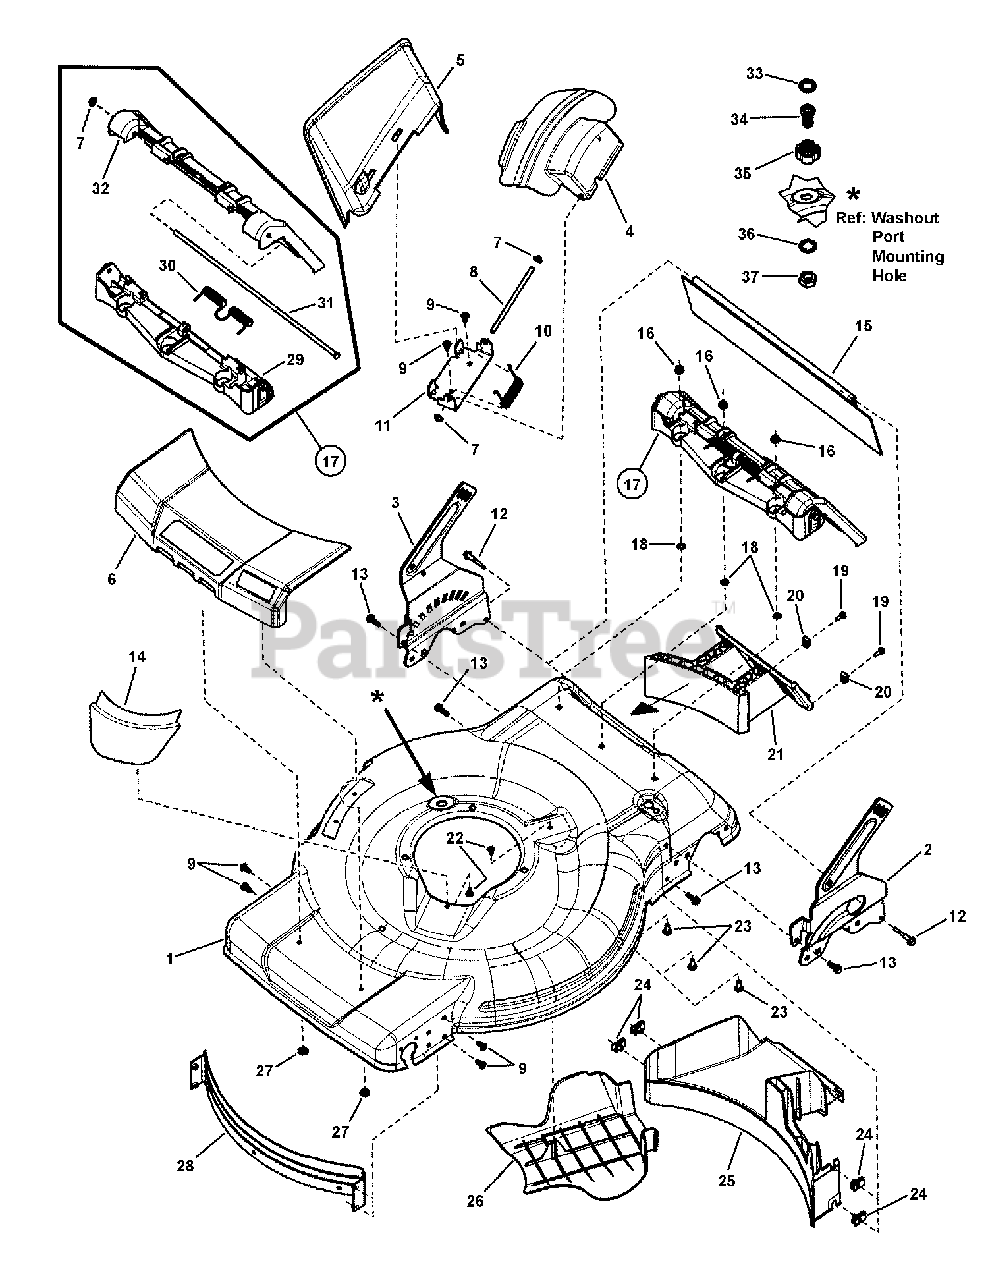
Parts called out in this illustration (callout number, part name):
1	DECK, 22", Rear Wheel Drive, Washout
1	DECK, 22", Rear Wheel Drive, Washout, Electric Start
2	BRACKET, Lower Handle, LH, 22 WBM
3	BRACKET, Lower Handle, RH, 22 WBM
4	COVER, Mulching
5	CHUTE, Side Discharge, 22" WBM
6	COVER, Front, Push/Rear Wheel Drive
7	PUSHNUT, 1/4"
8	ROD, Pivot
9	SCREW, 1/4-20 x .550 Self-Tap (Torx)
10	SPRING, Torsion
11	BRACKET, Chute
12	BOLT, 1/4-20 x 1-1/2" Shoulder
13	BOLT, 1/4-20 x 3/4" Hex Flange Lock, GR 5
14	DEBRIS SHIELD, Front
15	GUARD, Rear 22"
16	NUT, 1/4-20 Hex Flange Lock
17	ASSEMBLY, Door, 22" WBM
18	BOLT RETAINER, 1/4"
19	SCREW, #10-24 x 5/8" Hex Washer Face Self-Tap, GR 5
20	NUT, #10-24 Retainer Speed w/extrusion
21	PLUG, Mulching, 22" Deck
22	SCREW, Round Washer Head Torx, Hi-Lo
23	BOLT, 1/4-20 x 5/8" Flat Head Square Neck, GR 5
24	U-NUT, 1/4-20
25	BAFFLE, Rear, Rear Wheel Drive WBM
26	BELT COVER, Rear Drive
27	PUSH NUT, 3/16"
28	BAFFLE, Front
29	HINGE, Rear Discharge Door
30	SPRING, Torsion, Rear Door
31	ROD, Pivot, Rear Door
32	DOOR, Rear Discharge
33	WASHER, Hose
34	ADAPTOR, Washout Port, WBM
35	COUPLING, Hose
36	WASHER, 5/8" Internal Tooth Lock YZ
37	NUT, 5/8-11, NC-2B Black Hex Jam
